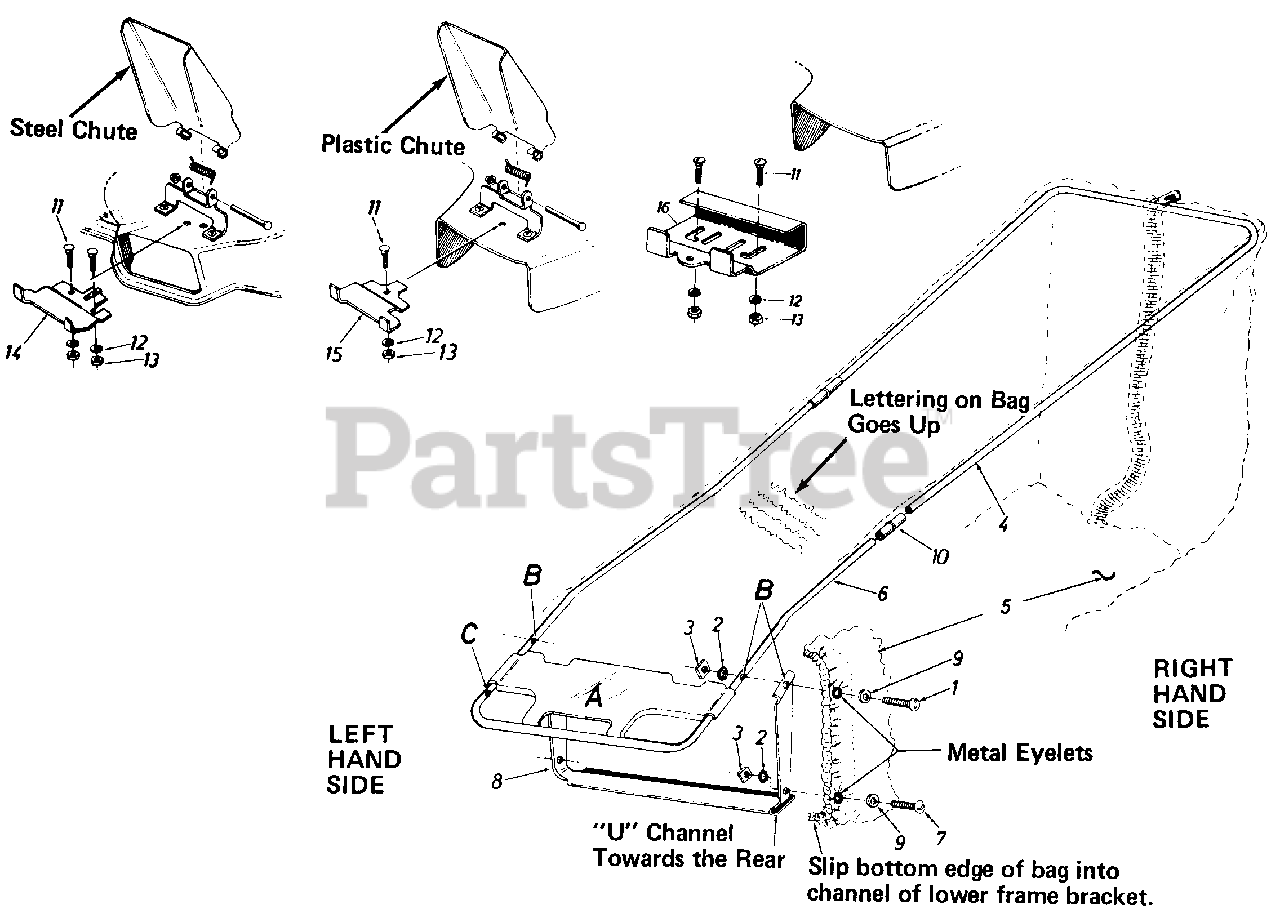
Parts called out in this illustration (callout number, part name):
1	Truss Mach. Scr. #10-24 x 1.00" Lg.*
2	Ext. L Wash. #10 Scr.*
3	Sq. Nut #10-24 Thd.*
4	Frame-Upper Half
5	Grass Catcher Bag
6	Frame-Lower Half
7	Truss Mach. Scr. #10-24 x .62" Lg.*
8	Lower Frame Bracket
9	Fl.-Wash. .203 I.D. x .41 O.D.
10	Tubing Connector
11	Carriage Bolt
12	Lock Washer 1/4" I.D.*
13	Hex Nut 1/4-2 Thd.*
14	Adapter Plate
15	Adapter Plate
16	Adapter Plate
